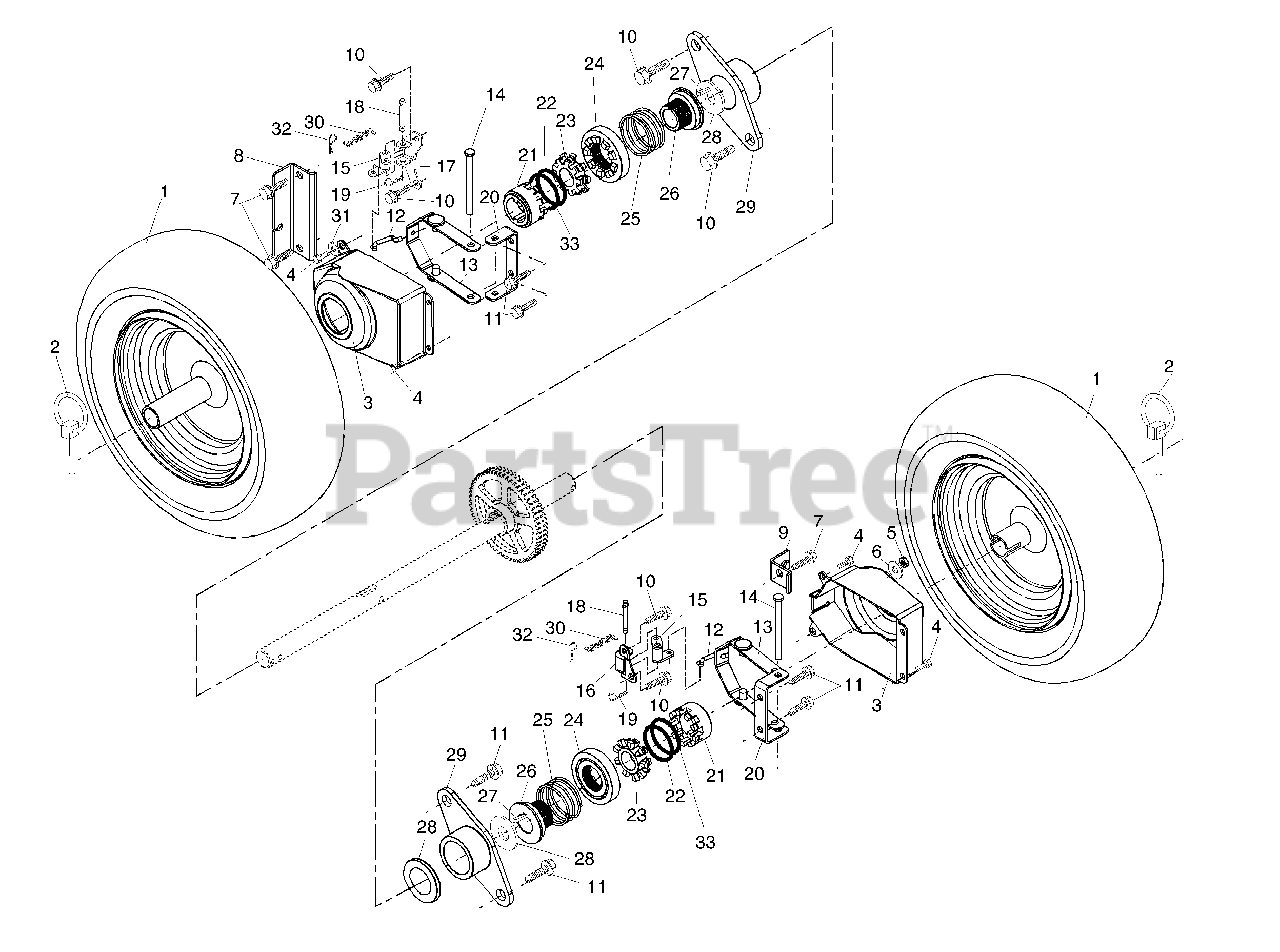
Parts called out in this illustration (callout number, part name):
1	Wheel Assembly (16" Power Steer)
2	Pin, Klik 1/4
3	Cover, Power Steering
4	Screw, Hex Head #10-24 x 1/2
5	Nut, Lock 5/16-18
6	Washer, Flat 5/16
7	Screw, Hex Head 3/8-16 x 1
8	Bracket, Steering Cable, RH
9	Bracket, Steering Cable, LH
10	Screw, Hex Head 5/16-18 x 3/4
11	Screw, Hex Head 5/16-18 x 1/2
12	Link, Steering Lever
13	Lever Assembly, Steering
14	Pin, Steering Lever
15	Bellcrank Assembly
16	Bracket Assembly, LH Steering
17	Bracket Assembly, RH Steering
18	Pin, Steering Bellcrank
19	Retainer, Hairpin
20	Bracket, Lever Assembly
21	Driver, Wheel
22	Ring, Wire Retainer
23	Lobe, Wheel
24	Slide, Clutch
25	Spring, Clutch Slide
26	Lobe, Axle
27	Key, Square 1/4
28	Washer, Thrust (1")
29	Bearing, Axle
30	Spring, Return
31	Washer, Flat
32	Clip, Retainer
33	Ring, Retaining
